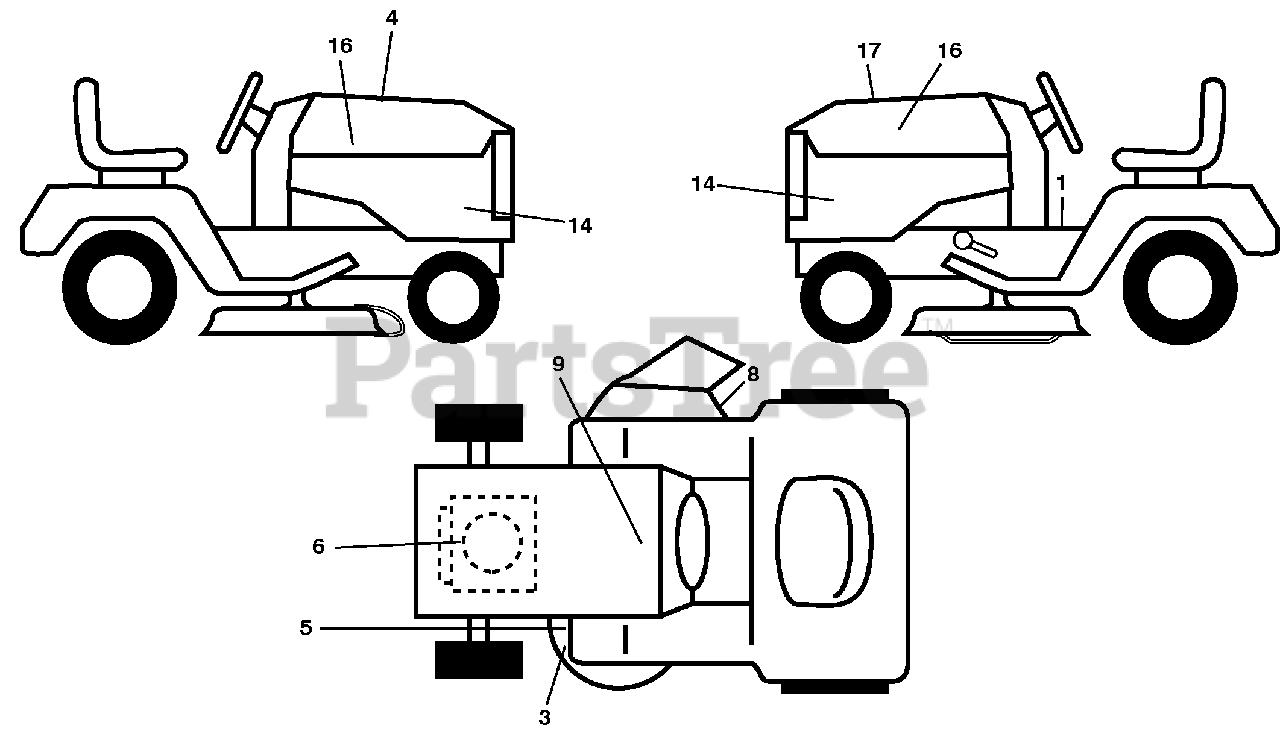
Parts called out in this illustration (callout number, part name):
1	Decal, Fender Warning
3	Decal, Warning
4	Decal, Hood Cust Resp
5	Decal, Caution
6	Decal, Eng. HP
8	Decal, Mower Sch.
9	Decal, Battery Dnge/Poi
14	Decal, Panel Side
16	Decal, Hood Logo
17	Decal, Replacement
